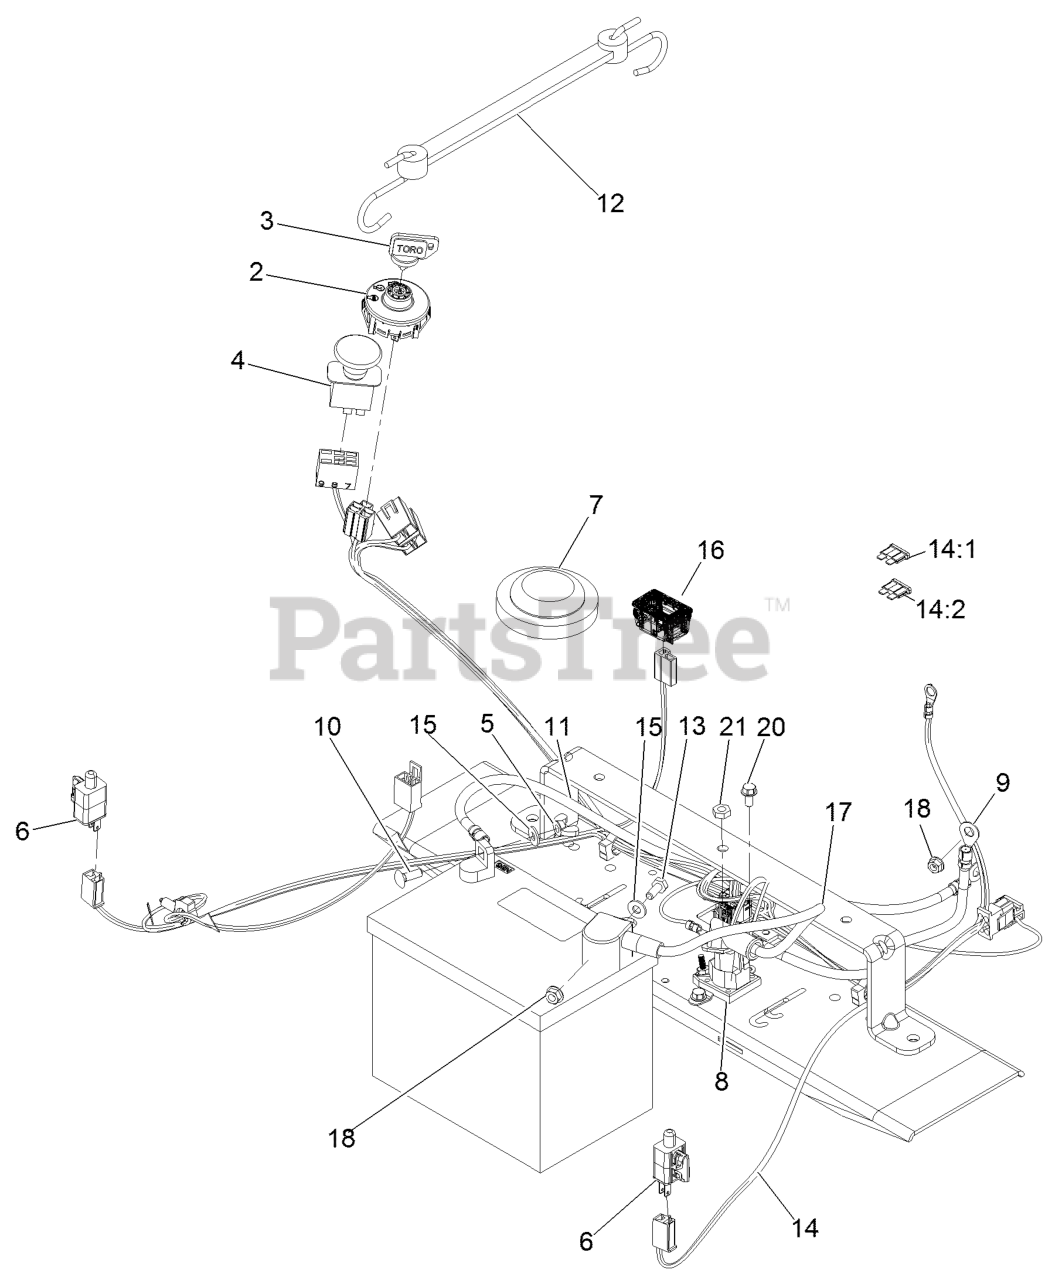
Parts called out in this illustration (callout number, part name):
3	KEY-IGNITION
4	SWITCH-PTO
5	NUT-WING
7	SWITCH-SEAT
8	SOLENOID
9	CABLE-BATTERY, POSITIVE
10	BOLT-CARR
11	CABLE-BATTERY, BLACK
12	HOLDDOWN-BATTERY
13	SCREW-HH
14:1	FUSE-BLADE, 30 AMP
14:2	FUSE-BLADE, 25 AMP
15	WASHER-FLAT
16	HOURMETER
17	CABLE-BATTERY, RED
20	SCREW-HWH
21	NUT-JAM
